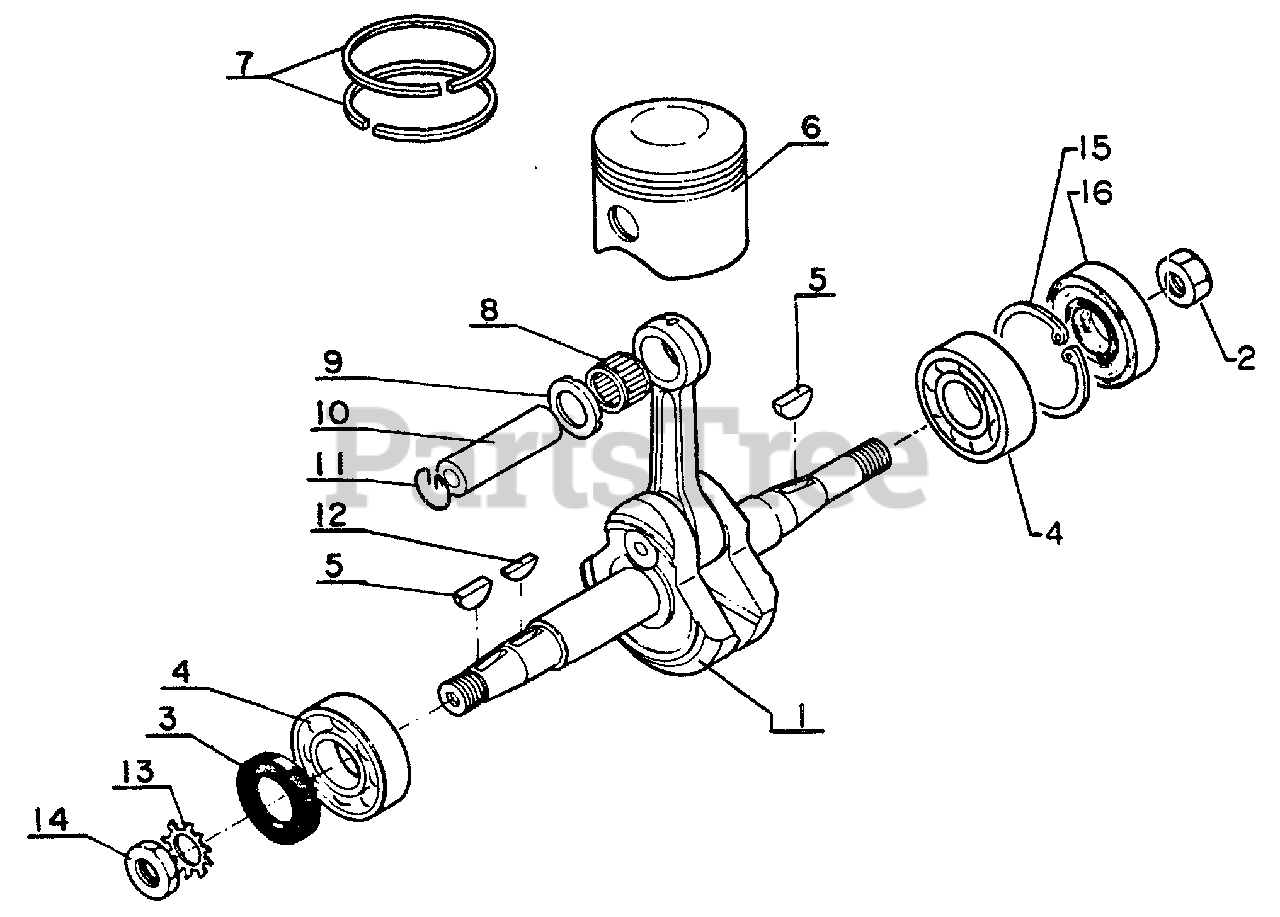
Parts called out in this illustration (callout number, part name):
1	CRANKSHAFT ASSY
3	SEAL, OIL
4	BEARING, BALL 6203 C3
5	KEY, WOODRUFF - 3×14
6	PISTON
7	RING, PISTON
8	BEARING, NEEDLE
9	WASHER, THRUST
10	PIN, PISTON
11	RING, SNAP
13	WASHER
15	RING, SNAP Ø40
16	SEAL, OIL
